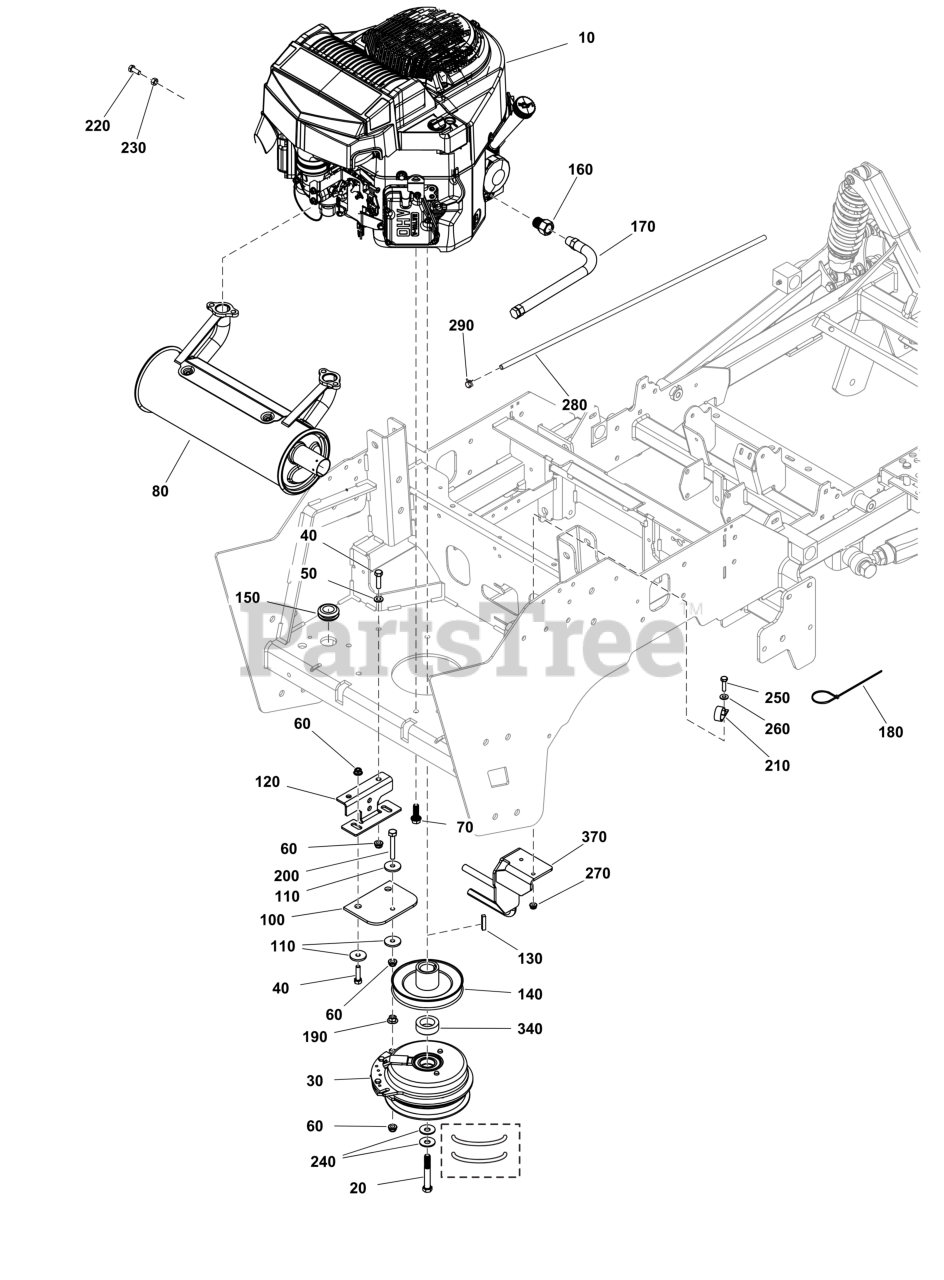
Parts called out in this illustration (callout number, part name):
20	BOLT, CRANKSHAFT, 7/1
50	WASHER
60	NUT
70	BOLT, FLANGE
100	CLUTCH ANCHOR PAD
110	WASHER, .34 X 1.25 X
120	ANCHOR, CLUTCH
130	KEY, 1/4 SQ X 1-1/4
140	PULLEY, Crankshaft
150	GROMMET, 7/8
160	ADAPTER, OIL DRAIN
170	HOSE, OIL DRAIN
180	TIE,SELF-LOCKING, 24"
190	NUT, 5/16-18 HEX SERR
200	BOLT, 5/16-18 X 2-1/4
220	CAPSCREW M8-1.25X16
230	NUT, HEX, M8-1.25
240	BELLEVILLE WASHER
250	BOLT, 1/4-20 X 1", GD
260	WASHER
280	HOSE, 1/4" FUEL, 8.00
290	CLAMP, Hose
310	SCREEN, SPARK ARRESTE
370	GUIDE, Belt
